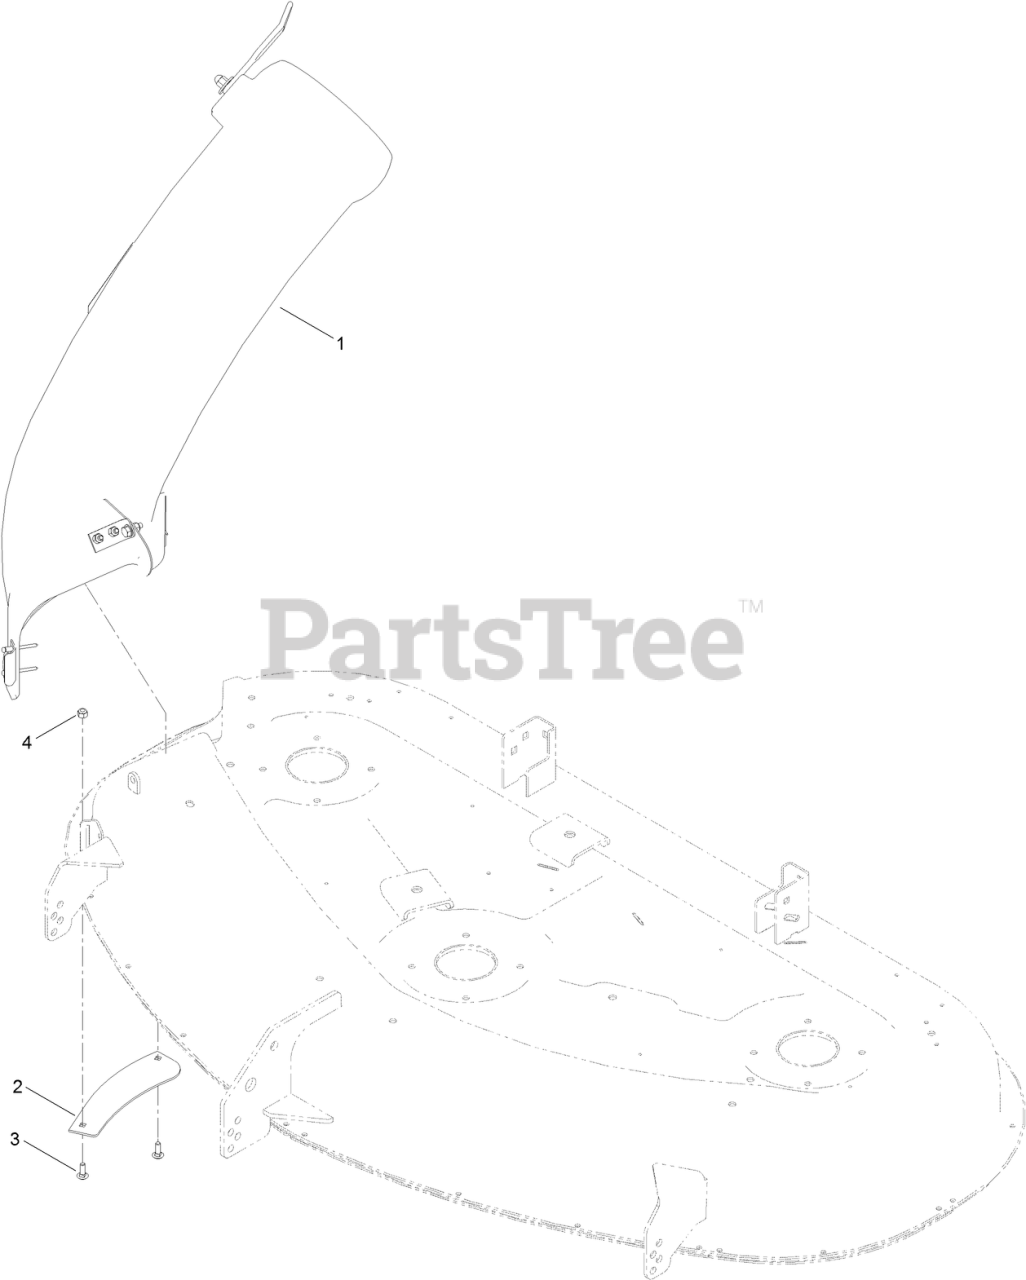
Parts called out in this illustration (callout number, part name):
1	CHUTE ASM-50"
2	BAFFLE-BLOWOUT
3	BOLT-CARR
4	NUT-HEX
